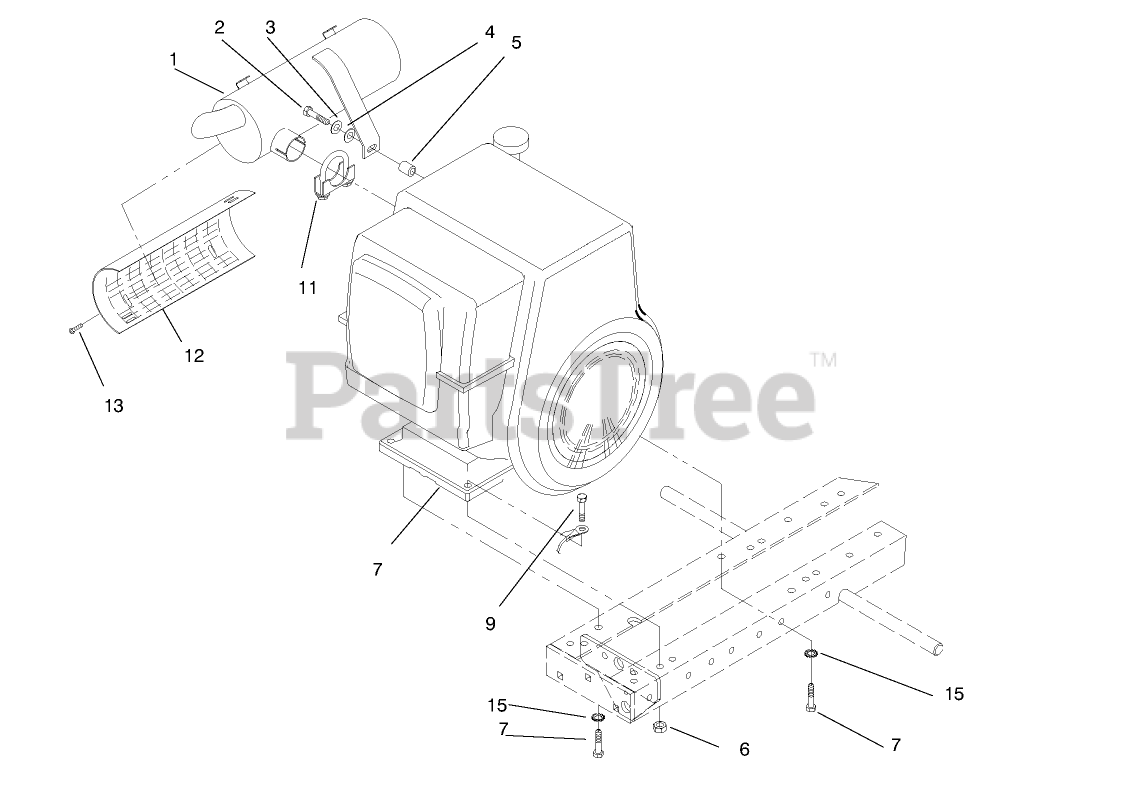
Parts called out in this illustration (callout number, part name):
1	MUFFLER
2	SCREW-HH
3	WASHER-LOCK
4	WASHER-PLAIN
5	SPACER
6	NUT-LOCK, NI
7	SCREW-HH
9	SCREW-HH
12	SHIELD-HEAT
13	SCREW
14	WIRE GROUND
15	WASHER-LOCK
